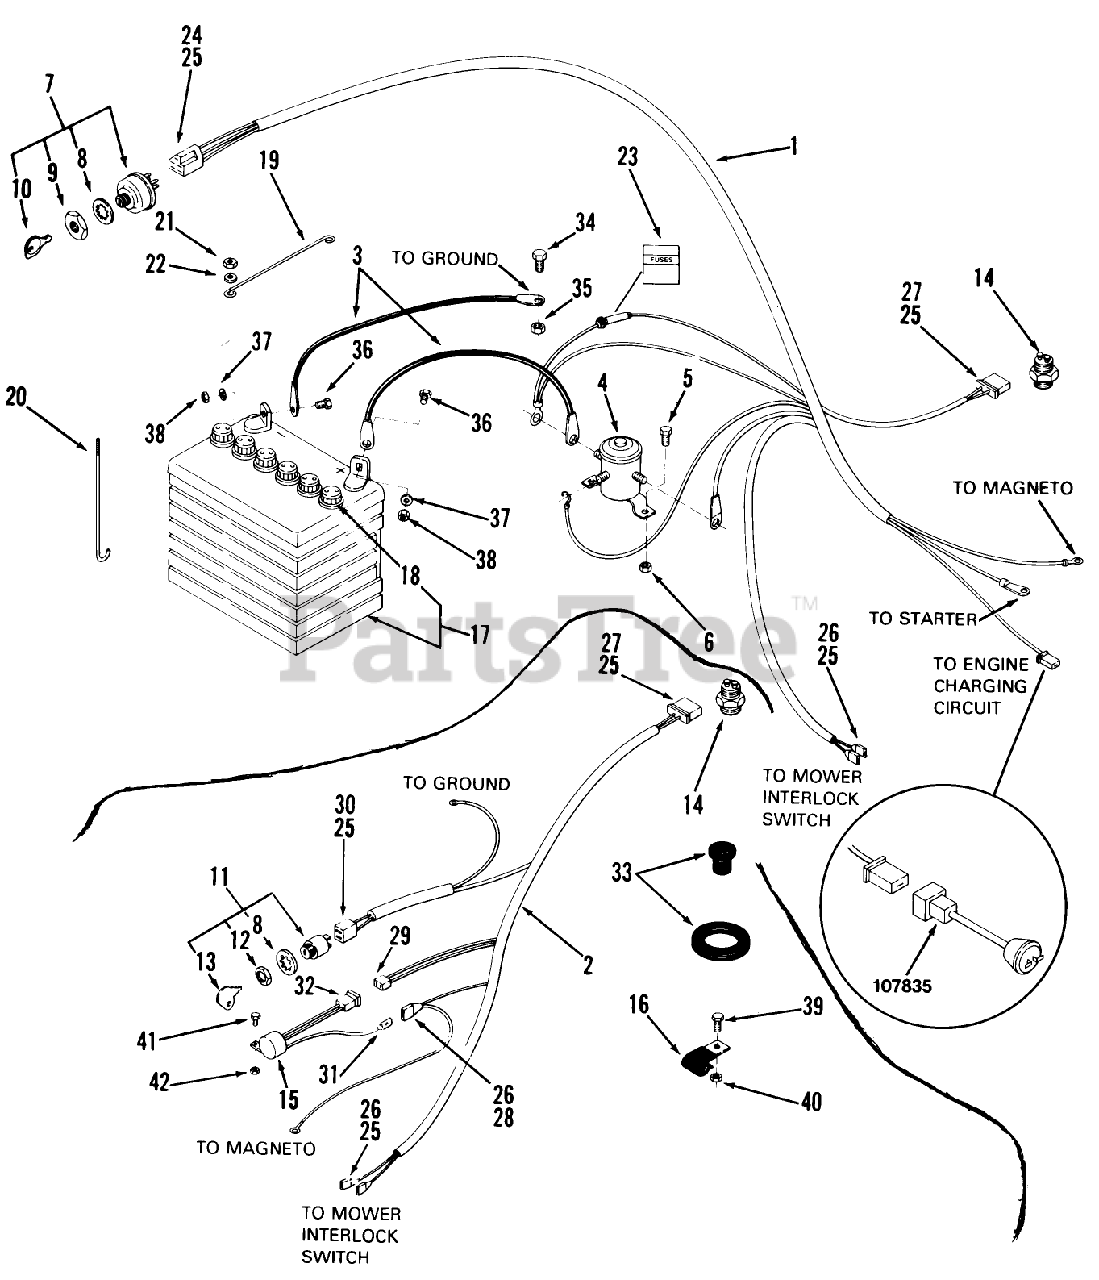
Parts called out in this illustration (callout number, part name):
7	ASSY-SWITCH IGNITION
9	NUT
12	NUT
16	CLIP
23	FUSE
26	CONNECTOR BODY ELECT
28	TERMINAL-TAB RCPT
33	GROMMET
